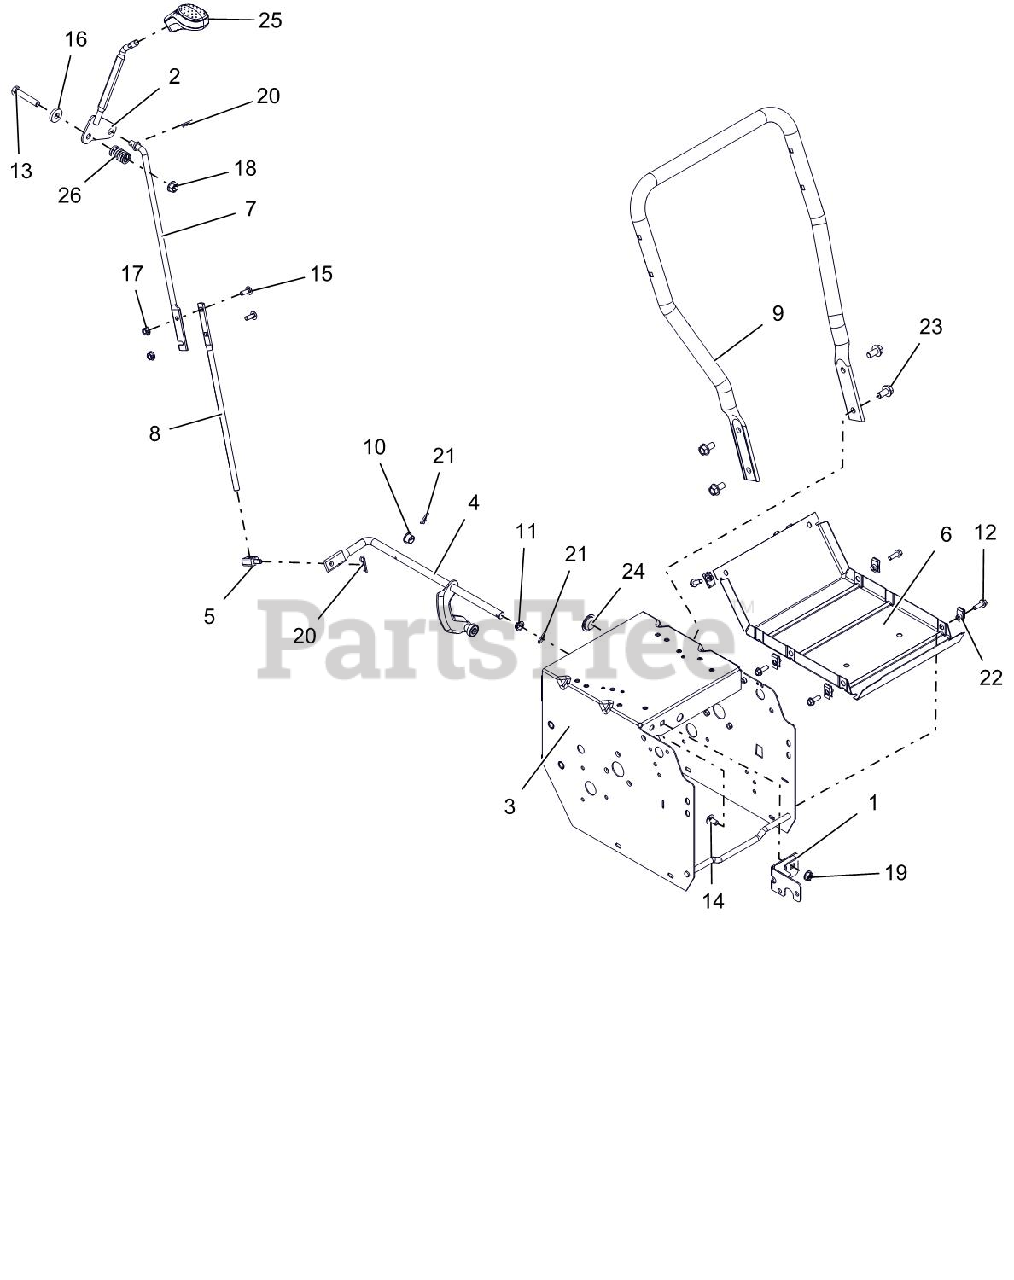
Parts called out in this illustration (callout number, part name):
1	WELDMENT, FRAME BRACKET
2	LEVER, CONTROL-SHIFT(WELDMENT)
3	WELDMENT, FRAME - DELUXE 16"
4	ARM, SHIFT-SMALL DASH (WLDMT)
5	PIVOT,SHIFT ROD .375-16(TRUNN)
6	COVER, BOTTOM
7	ROD, SHIFT - UPPER
8	ROD, SHIFT - LOWER(SMALL DASH)
9	HANDLEBAR, LOWER - SM DELUXE
10	BUSHING, POLYLINER-.50 SPLIT
11	BUSHING, POLYLINER-.50 SNAPIN
12	BLT-HEX .25-20X.75 HWH YZ GR5
13	@BLT-HEX .38-16X2.00 GR5 YWZC
14	@BLT-RHDSSQNK .31-18X.62 G5YZ
15	@BLT-RDHDSQNK .25-20X.75 G5YZ
16	WSHR-FL-STL .406X1.00X.188 YWZ
17	@NUT-LK-CTR-FLG .25-20 YWZC
18	@NUT-LK-TOP-FLG .38-16 YWZC
19	@NUT-LK-TOP-FLG .31-18 YWZC
20	PIN-HAIR INT .08X.18X1.18 YWZC
21	CLIP, SPRING
22	NUT-RTNR .25-20X.56
23	BLT-SERHFWH .38-16X.75 YWZC
24	PLUG, HOLE - .875" NYLON
25	KNOB, CONTROL, DASH
26	SG-COMP .125X.781X1.250
